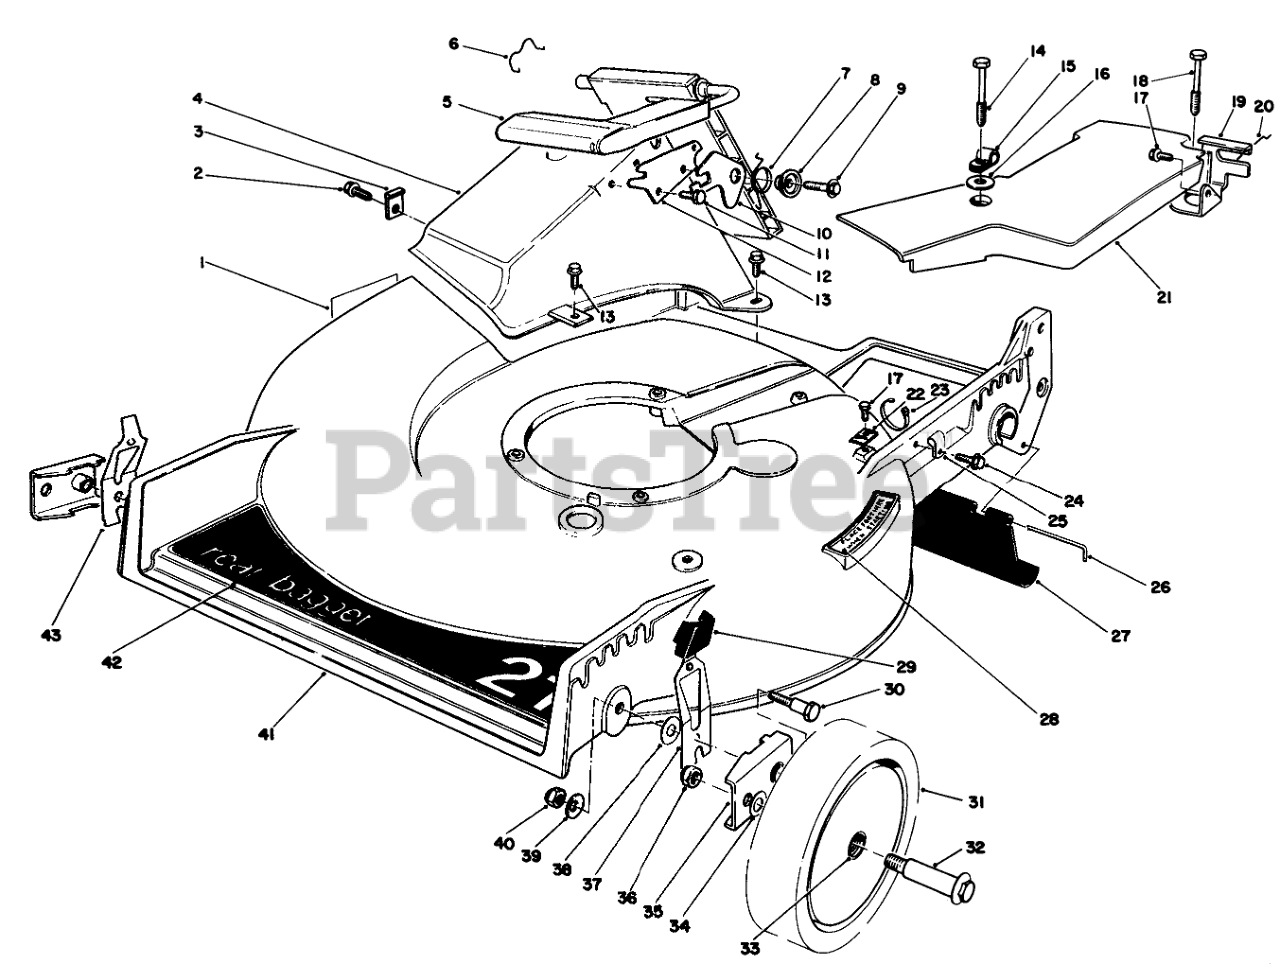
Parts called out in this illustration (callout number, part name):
1	DECAL-DANGER
2	SCREW
3	TUNNEL CLIP
4	Tunnel Discharge
5	Discharge Door Assembly
6	DOOR RET SPRING
7	TORSION SPRING
8	DOOR SPACER
9	SCREW-HWH
10	SAFETY LATCH
11	SCREW-PLASTITE
12	DOOR LATCH PLATE
13	SCREW-HWH
14	SCREW-SPECIAL
15	CLAMP-CABLE
16	WASHER
17	SCREW-HWHTF
18	SCREW-HHFTF
19	Bracket-Traction Adj.
20	RETAINER-CABLE
21	Belt Cover
22	CLAMP-CABLE
23	TIE-CABLE
24	SCREW
25	CLAMP-CABLE
26	ROD-SHIELD
27	SHIELD-TRAILING
28	STEP PAD DECAL
29	KNOB-ARM
30	PIVOT SCREW
31	Wheel & Tire Assembly (Incl. Ref. #33)
32	BOLT-WHEEL
33	BUSHING
34	WASHER
35	HP PIVOT ARM ASM
36	Nut
37	L. HP SPRING ARM ASM
38	WASHER-PIVOT
39	WASHER-BELLEVILLE
40	NUT-LOCK, NI
41	Housing (Incl. Ref. #1, 13 & 28)
42	DECK DECAL
43	R HP SPRING ARM ASM
